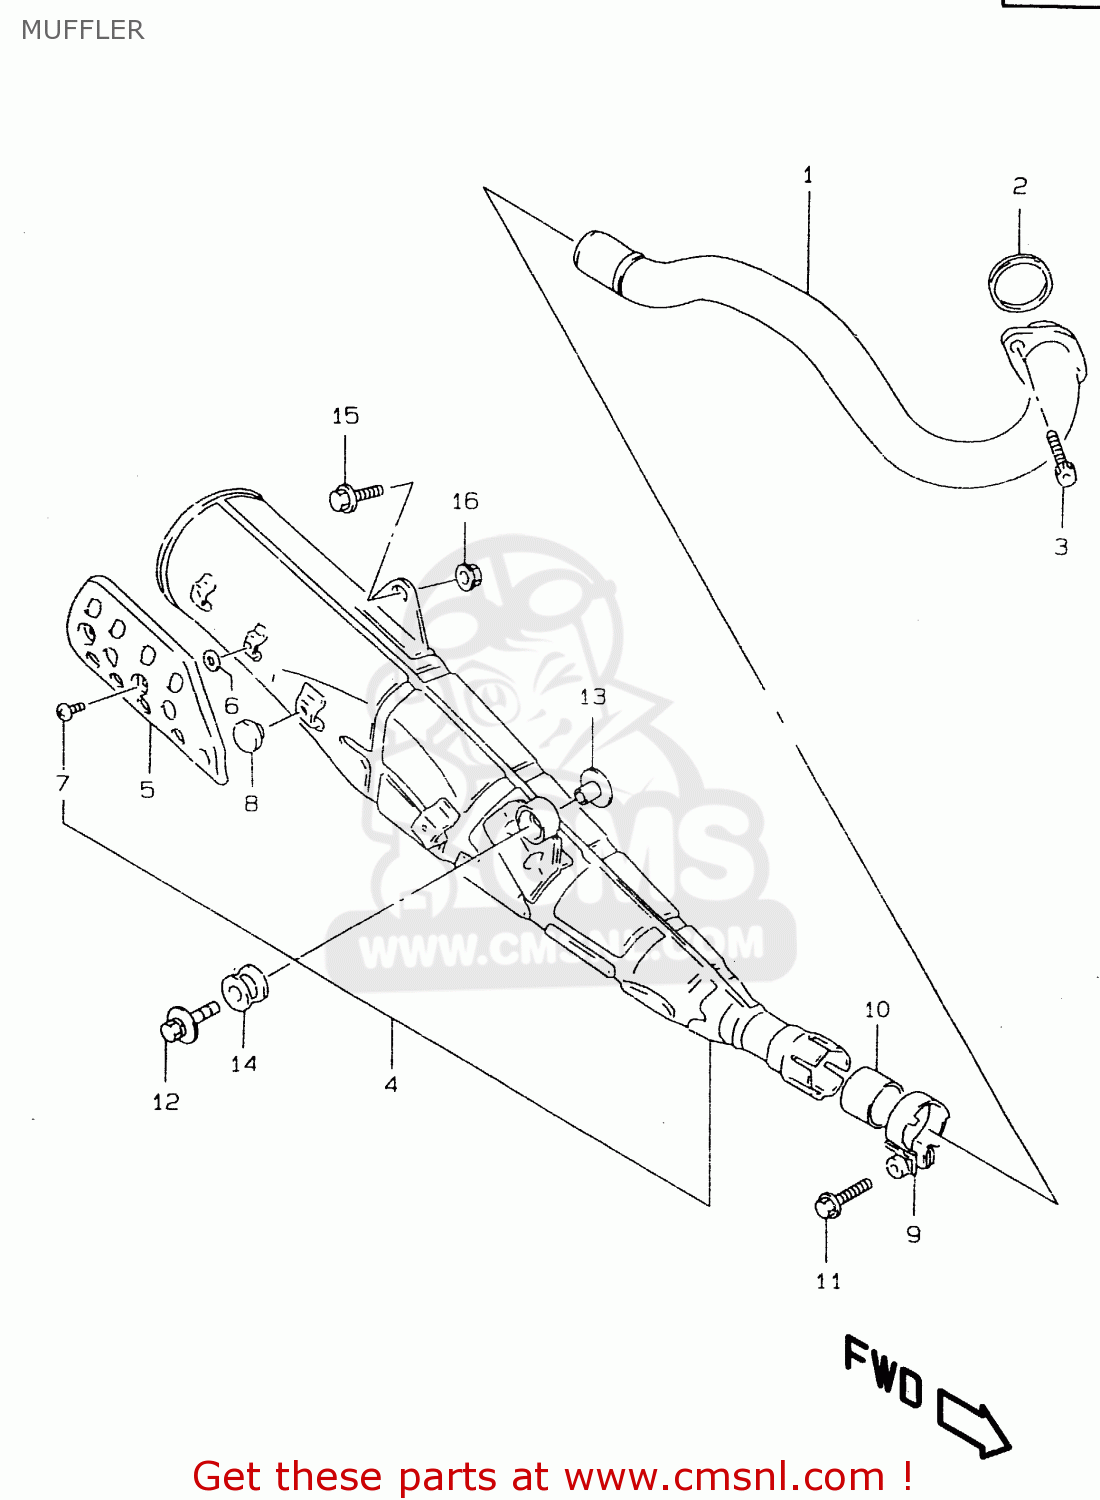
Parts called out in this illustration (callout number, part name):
1	PIPE,EXHAUST
2	GASKET,EXHAUST (NAS)
3	BOLT
4	MUFFLER ASSY
5	COVER,MUFFLER
6	GASKET(5.8X13X1.4) (NAS)
7	SCREW(6X10)
8	CUSHION
9	CLAMP,PREMUFFLER CONNECTOR,R
10	CONNECTOR,MUFFLER
11	BOLT
12	BOLT(8X35)
13	SPACER(8.6X12X17.5)
14	CUSHION
15	BOLT(8X35)
16	NUT
